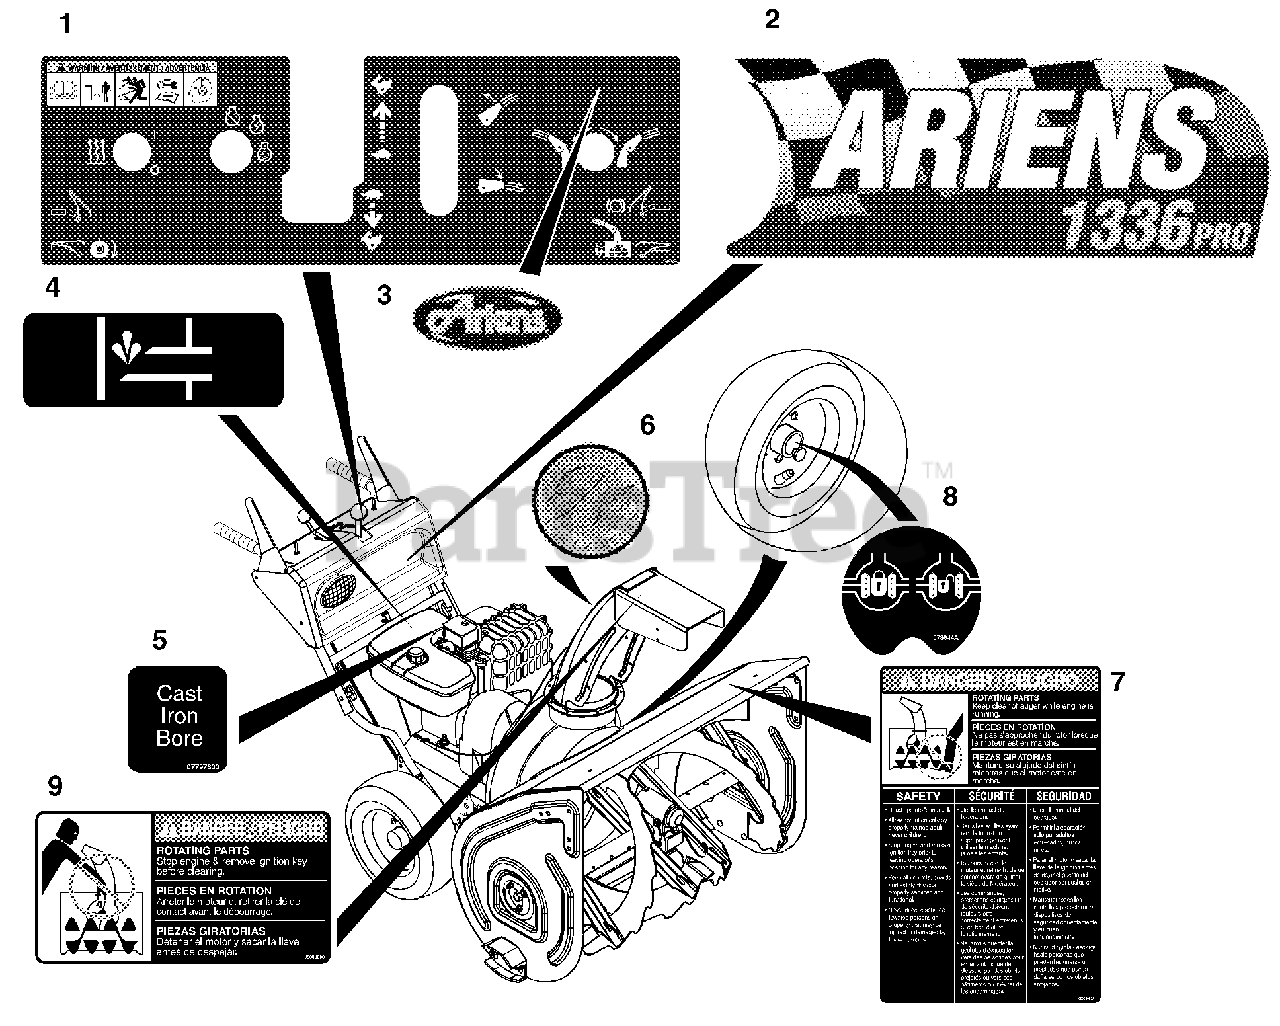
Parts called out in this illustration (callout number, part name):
1	DECAL, CONTROL - 1332, 1336
2	DECAL, FRONT PANEL - 1336
3	DECAL, "ARIENS" JEWEL
4	DECAL, PRIMER "TECUMSEH'S"
5	DECAL - CAST IRON BORE
6	DECAL, A+
7	DECAL, DANGER
8	DIFFERENTIAL LOCK DECAL
9	DECAL, DANGER - ROT. PARTS
